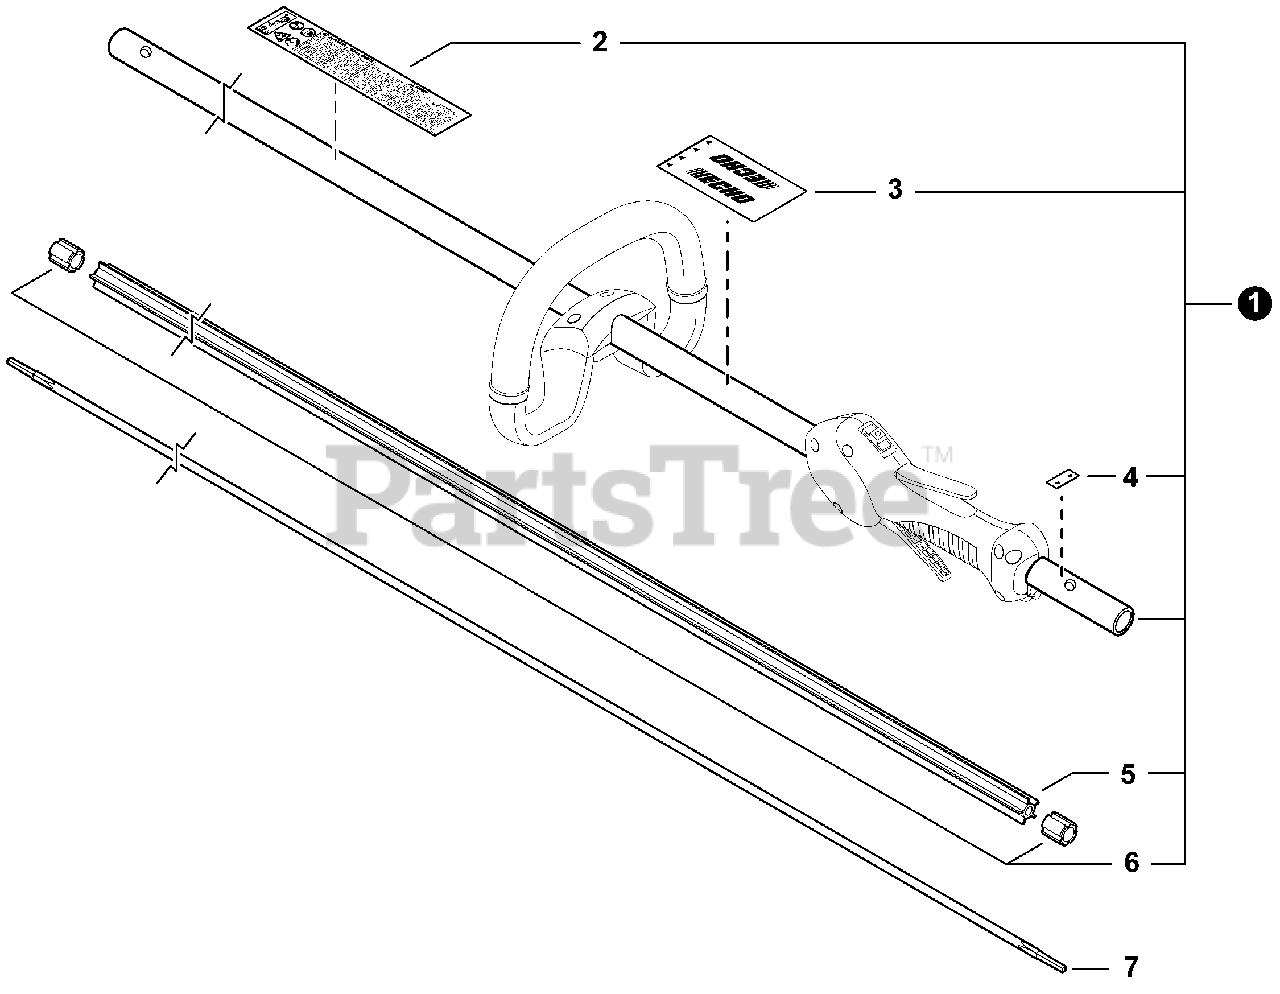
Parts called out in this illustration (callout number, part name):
1	MAIN PIPE ASSY
2	LABEL, CAUTION
3	LABEL, HANDLE LOCATION
4	LABEL - ALIGNMENT
5	LINER, FLEXIBLE 21.6×1420
7	DRIVESHAFT - FLEXIBLE L= 1522
